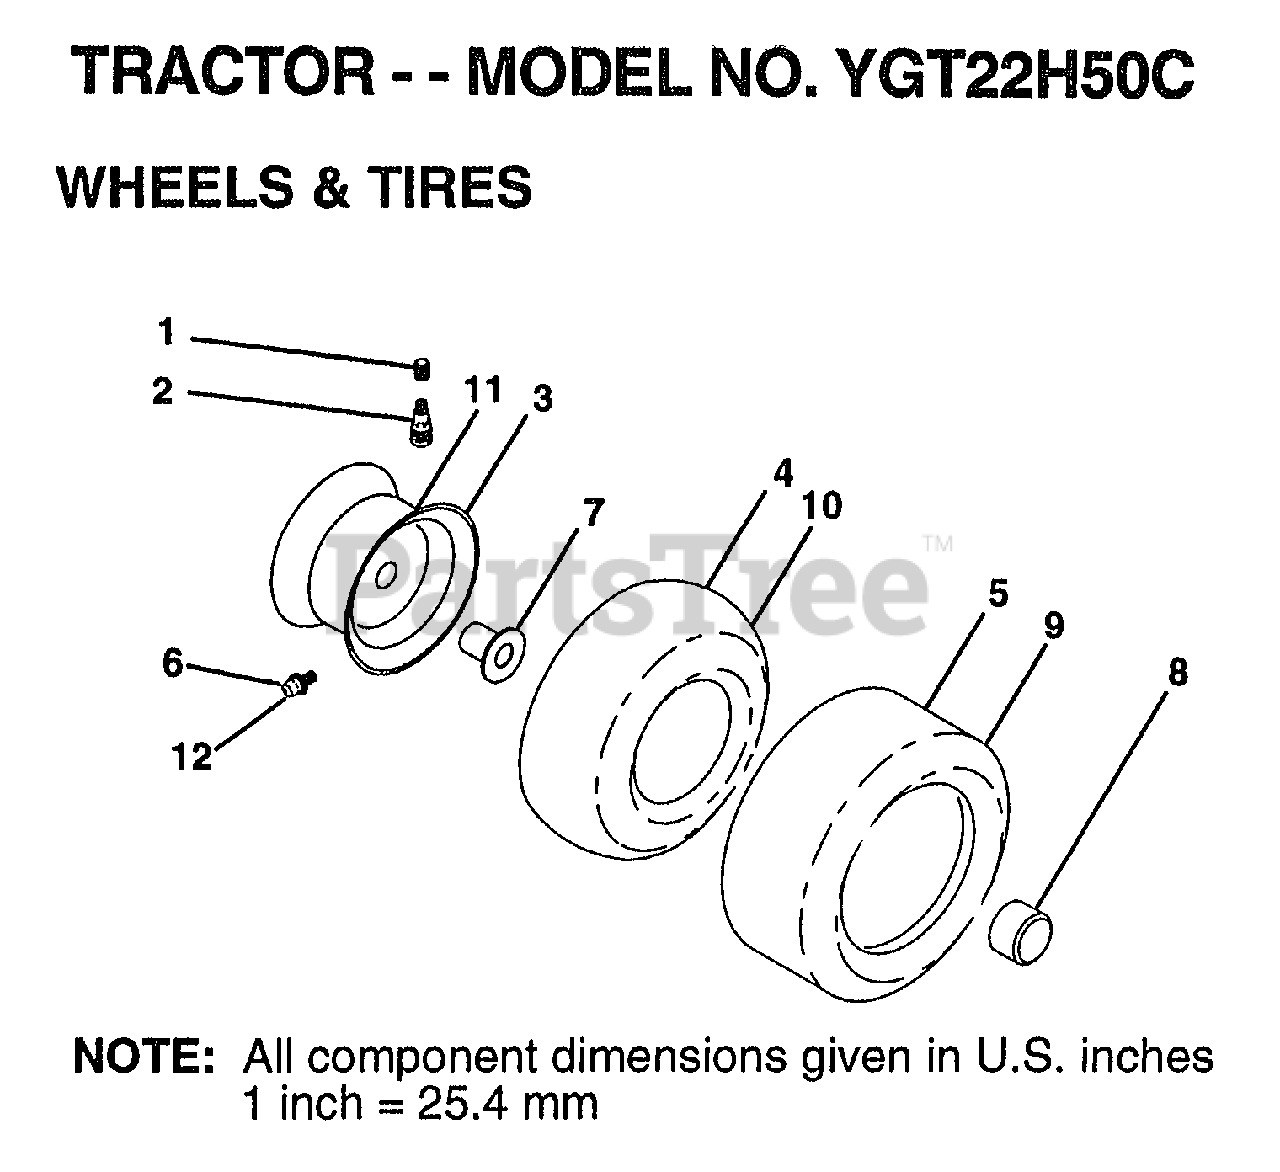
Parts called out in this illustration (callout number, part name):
1	VALVE CAP
2	VALVE STEM LT
3	"RIM ASM 8"" FRT"
4	TUBE.16X6.5/7.5-8
6	FITTING LT
7	"FLANGE, BEARING"
8	HUB CAP
10	TUBE.23X8/10-12
11	"RIM ASM 12"" REAR"
12	ZERK FITTING M
